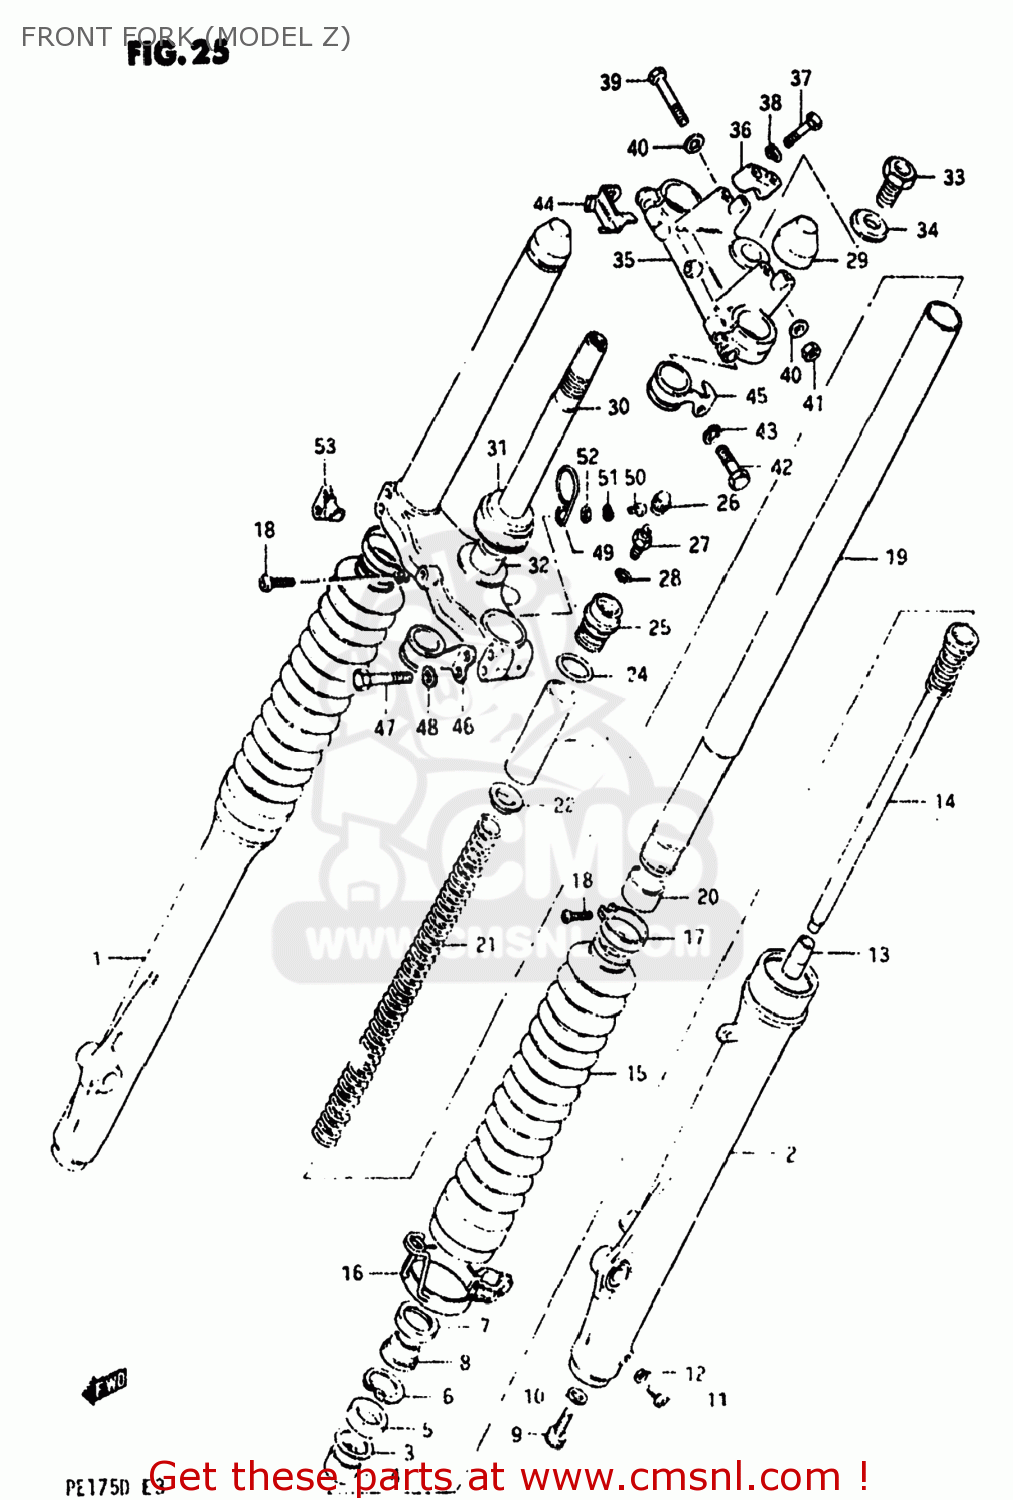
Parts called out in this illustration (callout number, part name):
1	TUBE,OUTER,RIGHT
2	TUBE,OUTER,LEFT
3	WASHER(40X50X2.3)
4	METAL,SLIDE
5	SEAL,OIL
6	RING,STOPPER
7	CASE,DUST SEAL
8	SEAL,DUST
9	BOLT,CYLINDER
10	GASKET,CYLINDER (NAS)
11	SCREW
12	GASKET,DRAIN,PLUG (NAS)
13	PIECE,OIL LOCK
14	CYLINDER,FRONT FORK
15	BOOT
16	BAND,FORK COVER BOOT
17	BAND,BOOT
18	SCREW 4X10
19	TUBE,FORK,INNER
20	PISTON
21	SPRING,FRONT FORK
22	GUIDE
23	SPACER,FRONT FORK SPRING
24	O RING
25	CAP,FORK INNER TUBE
26	CAP,VALVE
27	VALVE,FRONT FORK AIR
28	O-RING
29	CAP
30	STEM,STEERING
31	BEARING
32	WASHER,THRUST
33	BOLT
34	WASHER
35	HEAD,STEERING STEM
36	HOLDER,HANDLEBAR
37	BOLT
38	LOCK WASHER
39	BOLT 8X50
40	WASHER
41	NUT
42	BOLT
43	LOCK WASHER
44	BRACKET,TOOL FITTING,UPPER
45	GUIDE,CABLE
46	CLIP,CABLE
47	BOLT 8X45
48	LOCK WASHER
49	CLIP
50	SCREW
51	LOCK WASHER
52	WASHER
53	BRACKET,TOOL FITTING,LOWER
